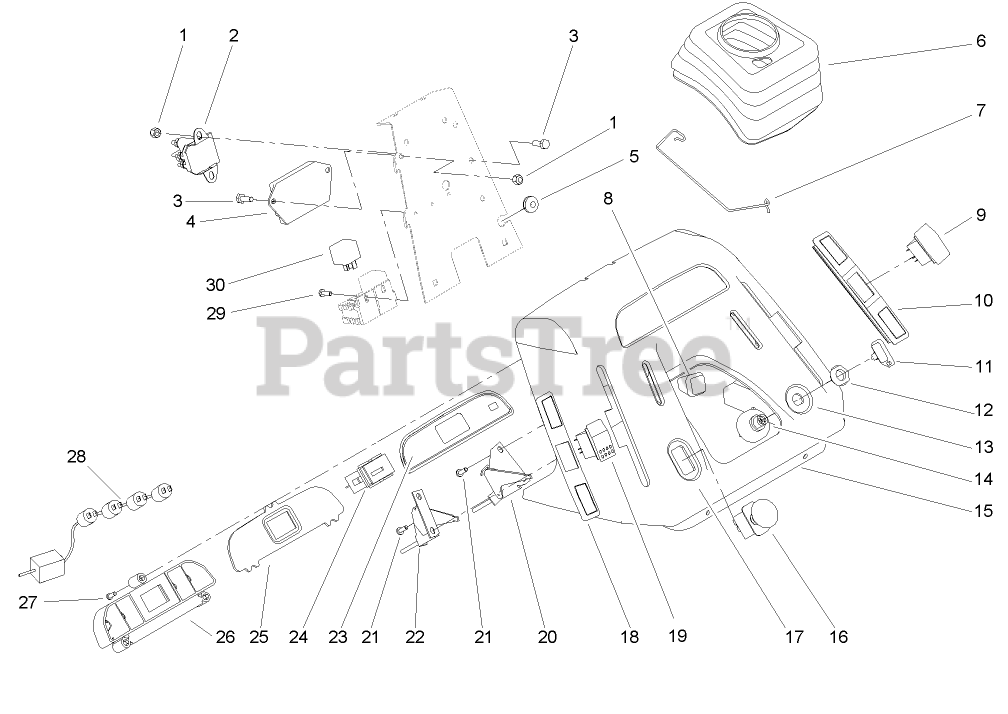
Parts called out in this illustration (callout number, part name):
1	NUT-LOCK, NI
2	SOLENOID-STARTER
3	SCREW-HH
4	MODULE-NMIR, LOW BATTERY
5	GROMMET-RUBBER
6	BOOT-STEERING
7	CLIP-BOOT
9	SWITCH-CRUISE
10	COVER-SLOT, RH
11	KEY-IGNITION
13	DECAL-THROTTLE, IGNITION
14	SWITCH-IGNITION
16	SWITCH-PTO,ON-ON-NONE
17	DECAL-PTO / CHOKE
18	COVER-LIFT
19	SWITCH
20	CONTROL-THROTTLE (TWIN)
22	CHOKE CONTROL ASM
23	DECAL-DASH, LENS
24	HOURMETER
25	LENS-DASH
26	HOUSING-LIGHT
27	SCREW
28	HARNESS-LIGHT, SIX
29	SCREW-PPHTF
30	RELAY
